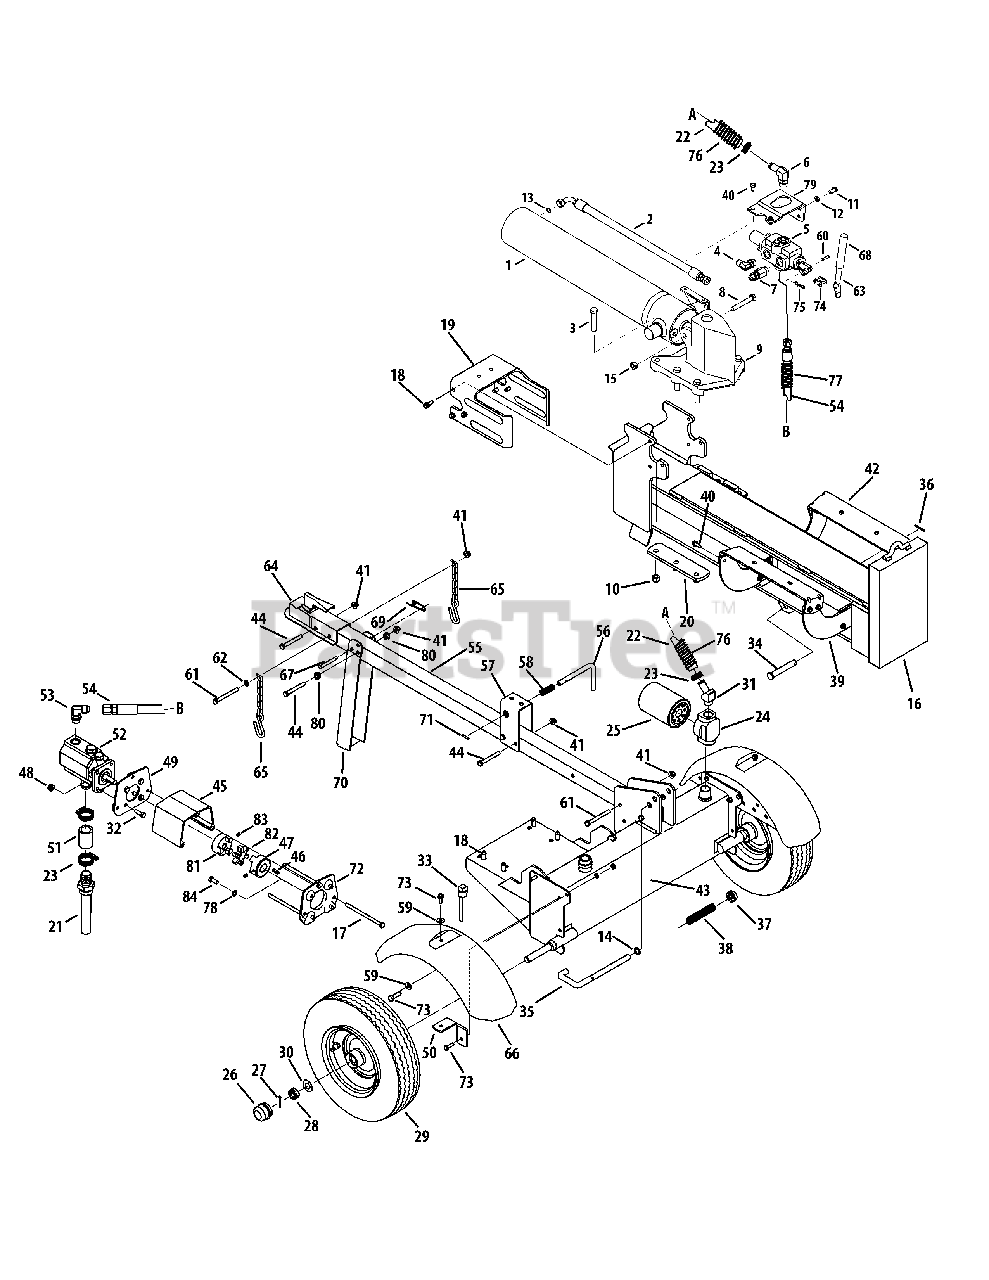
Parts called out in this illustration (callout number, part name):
1	Hydraulic Cylinder
2	Hydraulic Tube
3	Hex Cap Screw, 1/2-20 x 2.75
4	90 Degree Solid Adapter
5	Control Valve
6	Return Elbow
7	Nipple Pipe, 1/2-14
8	Hex Cap Screw, 1/2-13 x 3.25
9	Wedge Assembly
10	Hex Lock Nut, 1/2-20
11	Hex Cap Screw, 3/8-16 x .75
12	Lock Washer, 3/8
13	O-Ring, .489 ID x .070 Dia.
14	Flat Washer, .635 x.93 x.06
15	Hex Lock Nut, 1/2-13
16	Beam Assembly
17	Hex Screw, 5/16-18 x 4.00
18	Self Tapping Screw, 3/8-16 x 1.0
19	Dislodger Bracket
20	Back Plate
21	Inlet Filter
22	Return Hose, 3/4 x 44
23	Hose Clamp, 5/8
24	Filter Housing
25	Oil Filter
26	Hub Cap
27	Cotter Pin
28	Slotted Nut, 3/4-16
29	Complete Wheel Assembly
29	Dust Seal
29	Roller Bearing
30	Flat Washer, .760 x.500
31	Hydraulic Fitting, 1 1/16 Orb x .75
32	Hex Screw, 5/16-18 x 1.00
33	Vented Dipstick
34	Clevis Pin
35	Lock Rod
36	Cotter Pin
37	Push Cap
38	Compression Spring
39	Log Tray Bracket
40	Hex Washer Screw, 5/16-18 x .750
41	Flange Lock Nut, 3/8-16
43	Frame Assembly - MTD Engine
44	Hex Bolt, 3/8-16 x 3
45	Coupling Shield
46	Square Key, 3/16" x .75
47	Coupling, .750
48	Flange Lock Nut, 5/16-18
49	Rear Coupling Support Bracket
50	Fender Mounting Bracket
52	Gear Pump
53	45 Degree Elbow Fitting
54	High Pressure Hydraulic Hose
55	Tongue Assembly
56	Latch Rod
58	Compression Spring
59	Flat Washer
60	Clevis Pin
61	Hex Cap Screw, 3/8-16 x 3.50
62	Flat Washer, .375 x.738 x.063
63	Hydraulic Valve Control
64	Hitch Coupling Assembly
66	Fender
67	Clevis Pin
69	Spring Pin
70	Jack Stand
71	Spiral Pin
72	Front Coupling Support Bracket
73	Self-Tapping Screw, 5/16-18 x 1.00
74	Valve Handle Link
75	Cotter Pin, Bow Tie
76	Hose Guard, 48"
77	Hose Guard, 44"
78	Lock Washer, 5/16
79	Outer Valve Bracket
80	Plastic Bushing, .380 ID
81	Coupling, .500
82	Spider Bushing
83	Set Screws
84	Hex Cap Screw, 5/16-24 x .75
